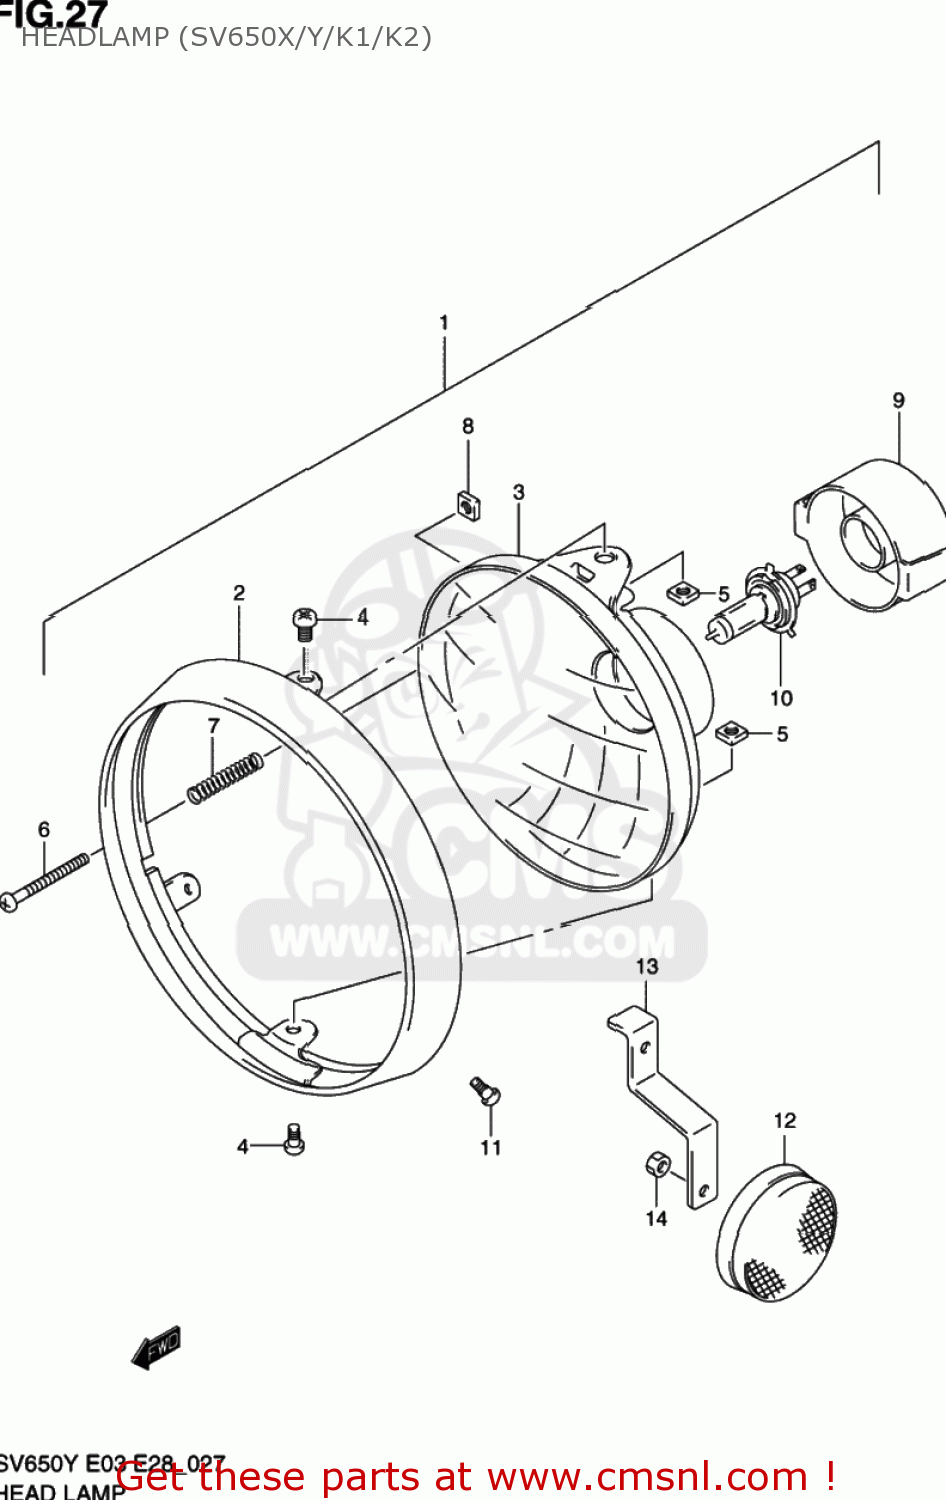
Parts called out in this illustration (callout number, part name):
1	HEADLAMP ASSY
2	RIM
3	LAMP UNIT
4	SCREW(5X16)
5	NUT
6	SCREW,ADJUSTING
7	SPRING
8	NUT,HEADLAMP ADJUST
9	COVER,SOCKET
10	BULB(12V60/55W,H4)
11	SCREW(5X15.3)
12	REFLECTOR,REFLEX FR
13	BRACKET,FR SIDE RR
14	NUT
